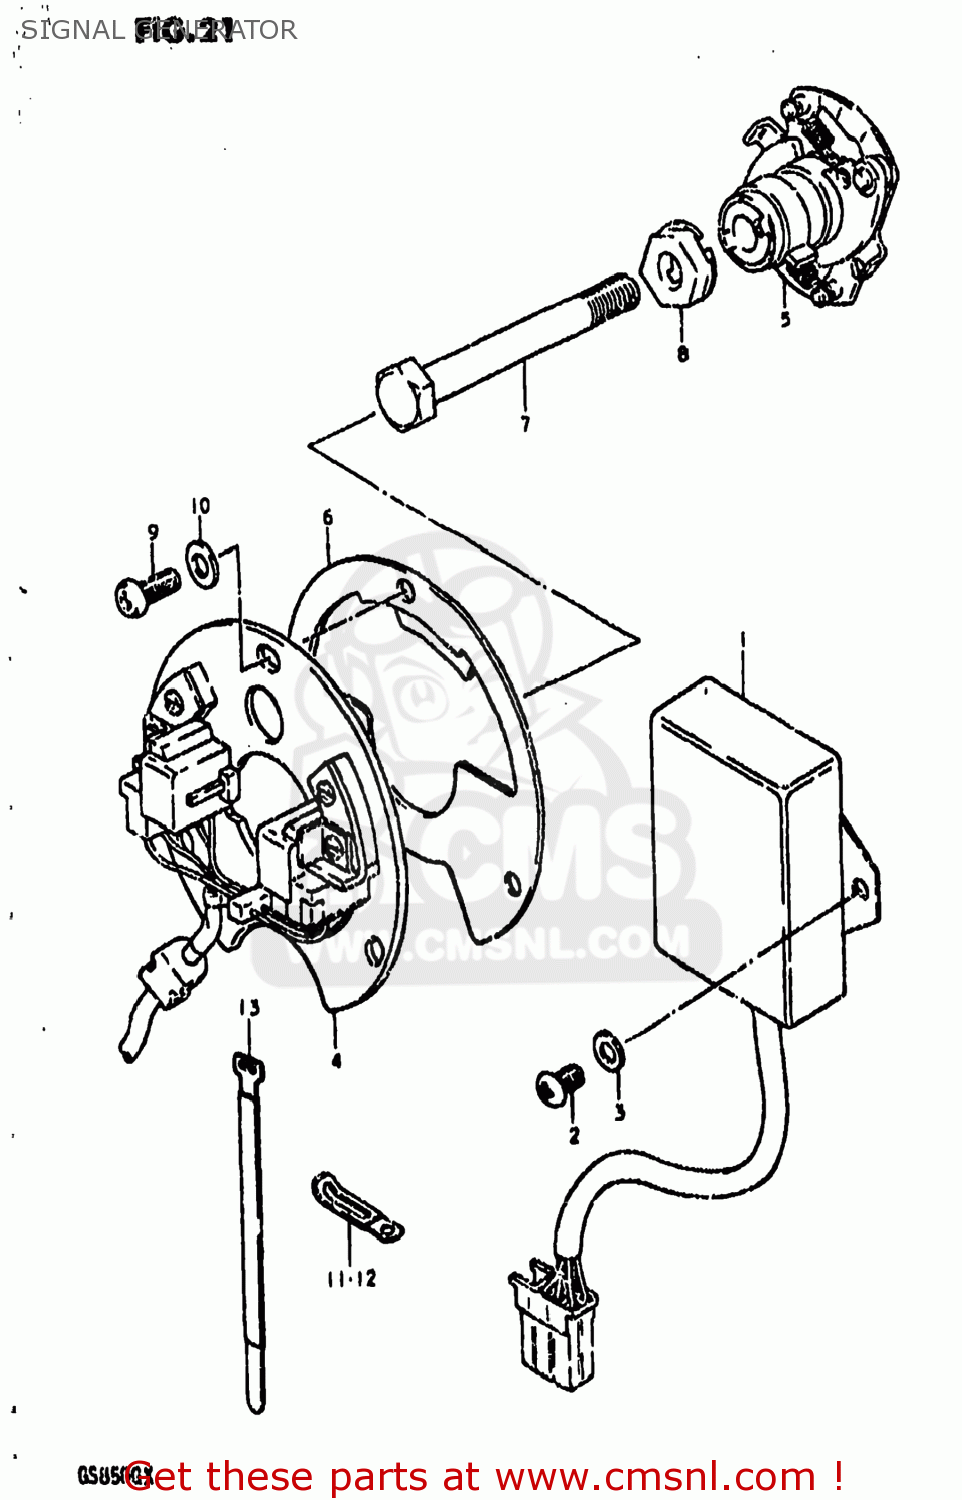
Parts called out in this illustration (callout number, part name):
1	IGNITER UNIT
2	SCREW
3	WASHER
4	SIGNAL GENERATOR ASSEMBLY
5	GOVERNOR ASSEMBLY
6	PLATE,TIMING
7	BOLT
8	WASHER
9	SCREW(5X12)
10	WASHER
11	CLAMP L:35
12	CLAMP
13	CLAMP
